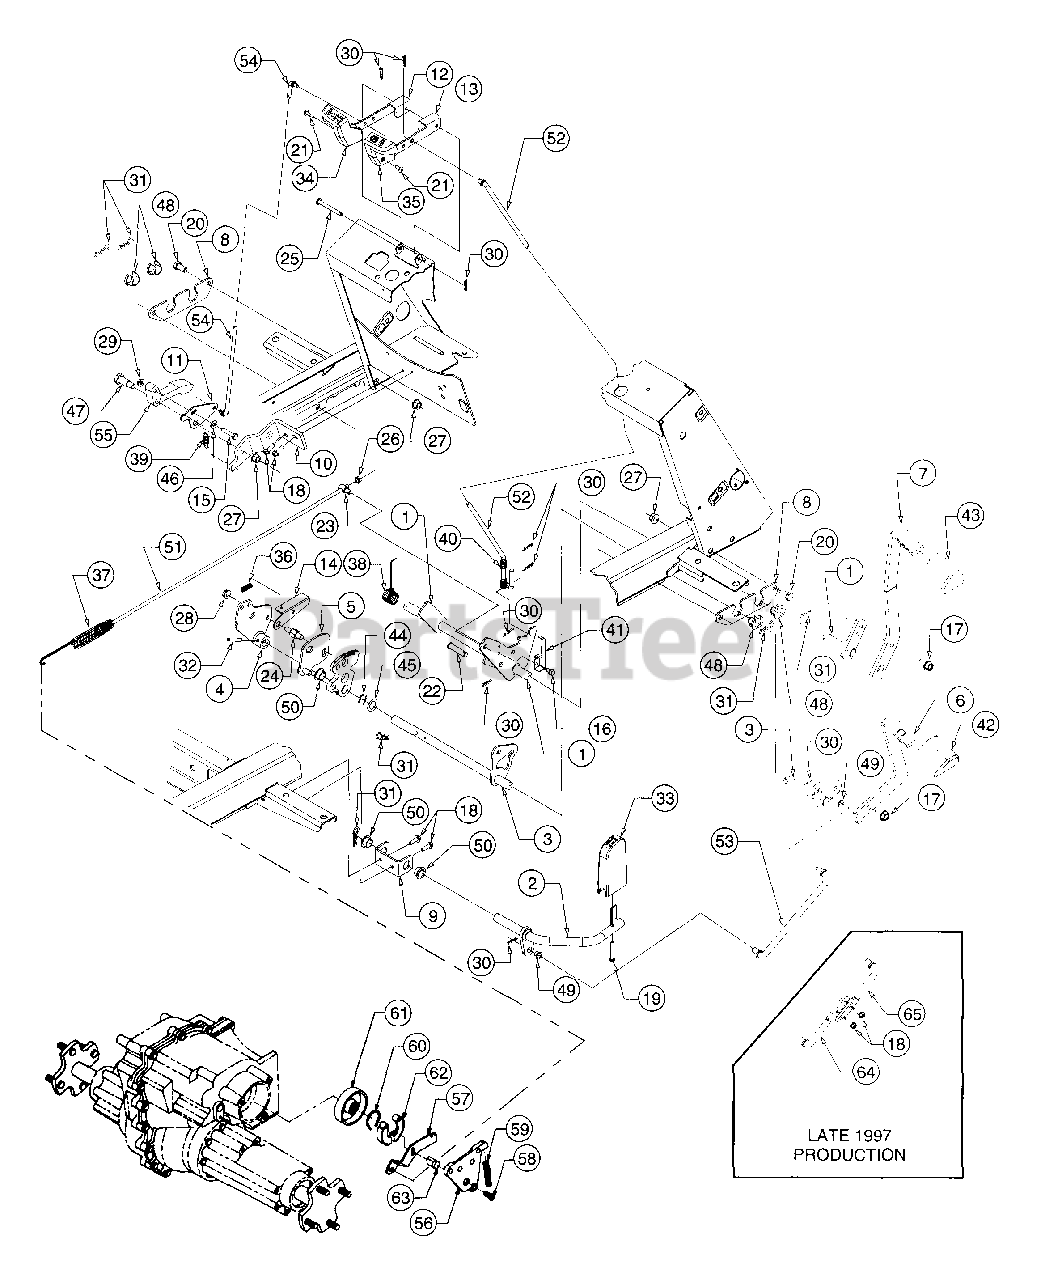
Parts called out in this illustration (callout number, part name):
1	Shaft Assy, Brake
4	Cam Assy, Control
5	Plate Assy, Disengagement
6	Pedal, Forward
7	Pedal, Brake
8	Plate, Bearing Mounting
10	Bracket, Cruise
11	Plate, Rod Adjustment
15	Screw, Hex Cap, 1/4-20 x 1.25
16	Screw, Hex Wshr Tap 1/4-20 x .5
17	Screw, Hex Wshr Tap 3/8-16 x .75
18	Screw, Hex Wshr Tap 1/4-20 x .75
19	Screw, Truss Mach, #12 x 1.5
20	Screw, Hex Cap, 3/8-16 x .75 GR5
21	Screw, Phil Hd Pan, #10-24 x .75
22	Pin, Clevis, 3/8 x 1.62
23	Ferrule, Adjustment, 1/4-20 Thrd
24	Stud, Actuator
25	Pin, Clevis, .25 x 2.38 Lg
26	Nut, Hex Sems, 1/4-20
27	Nut, Hex Flange Lock, 3/8-16
28	Nut, Hex Flange Lock, 5/16-18
29	Nut, Hex Flange Lock, 1/4-20
30	Pin, Int Cotter, 5/16 Dia x 1.12 Lg 9
31	Pin, Int Cotter, 3/8 Dia x 1.62
32	Pin, Spiral Spring, 1/4 x 1.5
33	Pedal, Reverse
34	Knob, Cruise
35	Knob, Brake Lock
36	Spring Extension .38 OD x 2.1
37	Spring, Extension
38	Spring, Torsion
39	Spring, Ext, .437 OD x 1.32
40	Spring, Compression, .50 x 2.23
41	Spring, Switch Actuator
42	Pad, Forward Foot Control
43	Pad, Brake Foot
44	Washer, Wave, .625 x .885 x .015
45	Washer, Flat, .635 x 1.0 x .020
46	Washer, Flat, 1/4 x .63 x .051
47	Shoulder Bolt, .50 OD x.840
48	Bearing, Hex Flange Split
49	Bearing, Flange, .375 x .58 x .25
50	Bearing, Flange, .626 x .93 x .344
51	Rod, Brake
52	Rod, Parking Brake
53	Rod, Connecting
54	Rod, Cruise
55	Latch, Cruise
56	Plate, Brake
57	Arm, Brake
58	Screw, Low Hd Cap, 3/8-16 x .75
59	Spring, Compression
60	Spring, Brake
61	Drum, Brake
62	Shoe, Brake
63	Actuator, Brake Shoe
64	Rod, Rear Connecting
65	Rod, Front Connecting
